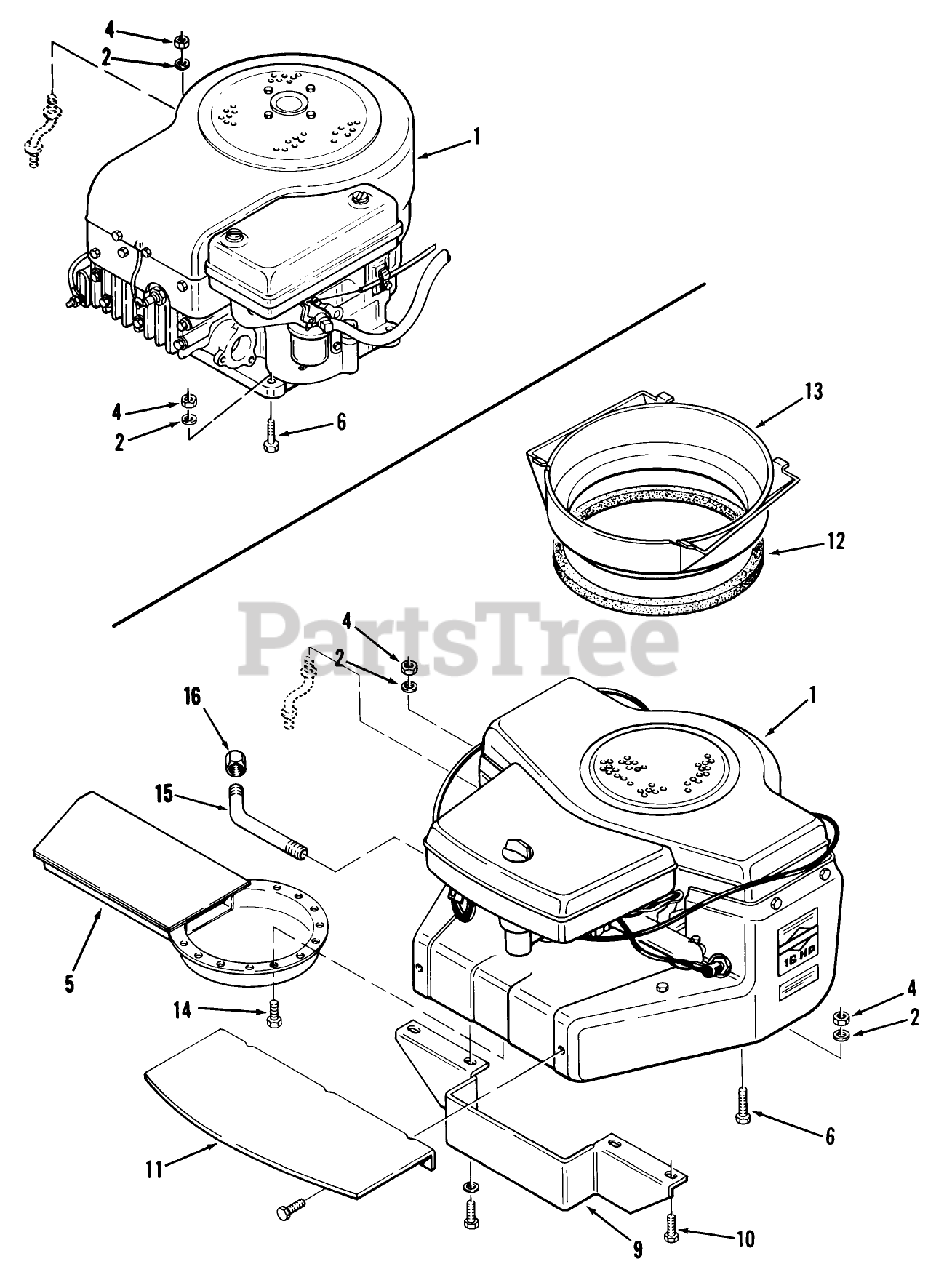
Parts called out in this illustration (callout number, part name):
1	Engine-11HP-BS Model 252707, Type 0222-02
1	Engine-16HP-BS Model 402707, Type 0130-03, LT-1637 Only
1	Engine-8HP-B S Model 191707, Type 1160-02-LT-832 Only
1	Engine-10HP-Tecumseh Model TVM 220-157063D-LT-1032 Only
2	WASHER 5/16 SAE
13	DUCT-AIR INTAKE
